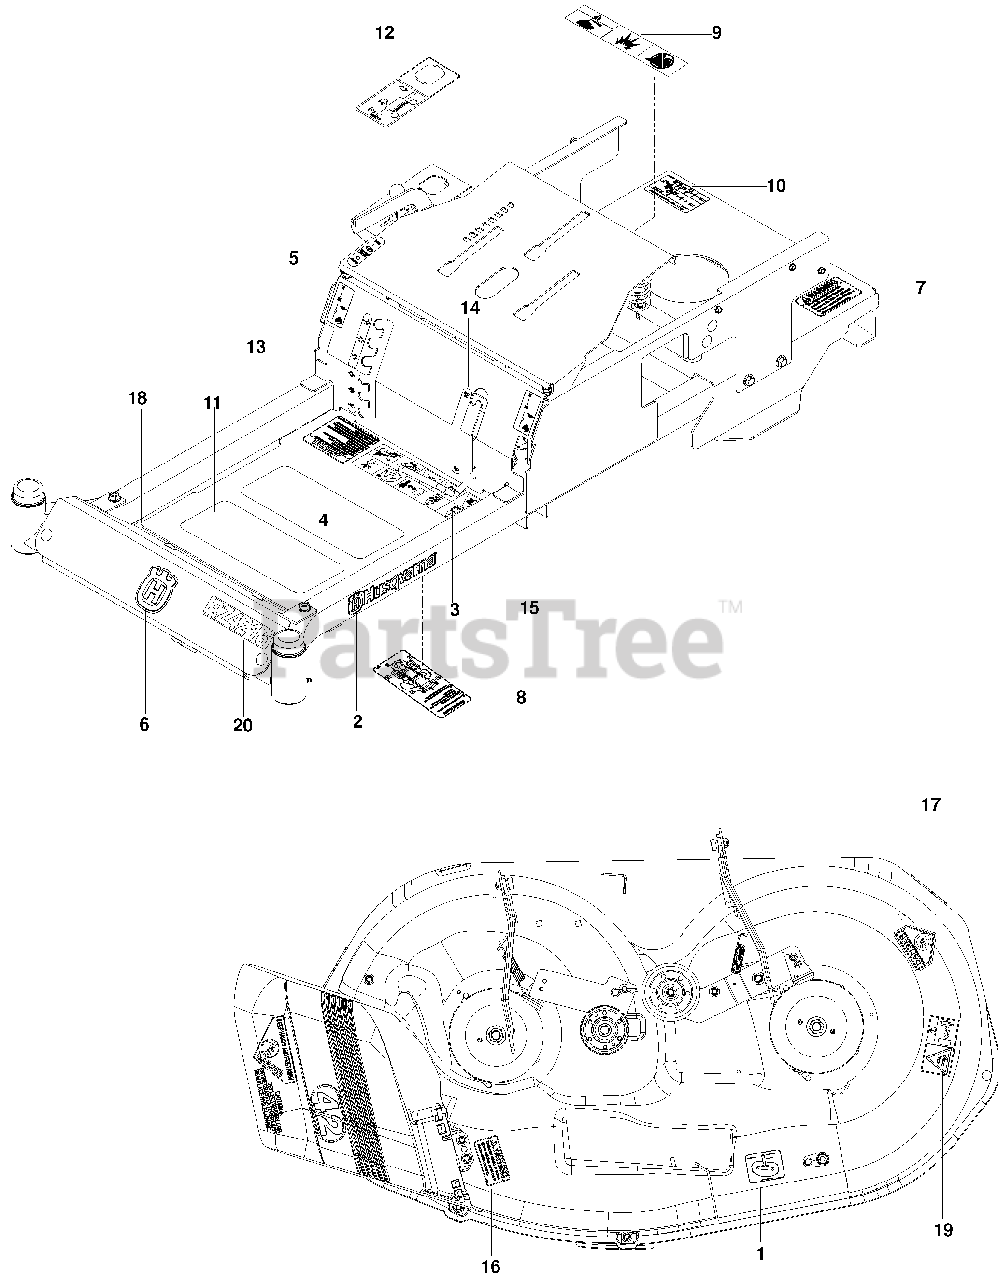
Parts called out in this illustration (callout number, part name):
1	DECAL, BELT ROUTING
2	DECAL, HUSQVARNA
3	DECAL, SAFETY WARNING
4	DECAL, WARNINGS
5	DECAL, PARK BRAKE
6	DECAL, CROWN
7	DECAL, PROP 65
8	DECAL, SERVICE
9	DECAL, BATTERY WARNING
10	DECAL, DO NOT TOW
11	PAD, ABRASIVE
12	DECAL, CONTROL PANEL
13	DECAL, DECK HEIGHT
14	DECAL, BLADE ENGAGE
15	DECAL, MOTION CONTROL
16	DECAL, DEFLECT WARNING
17	DECAL, BLADE WARNING
19	DECAL, SEVERING
20	DECAL, RZ4216
21	DECAL, 42"
